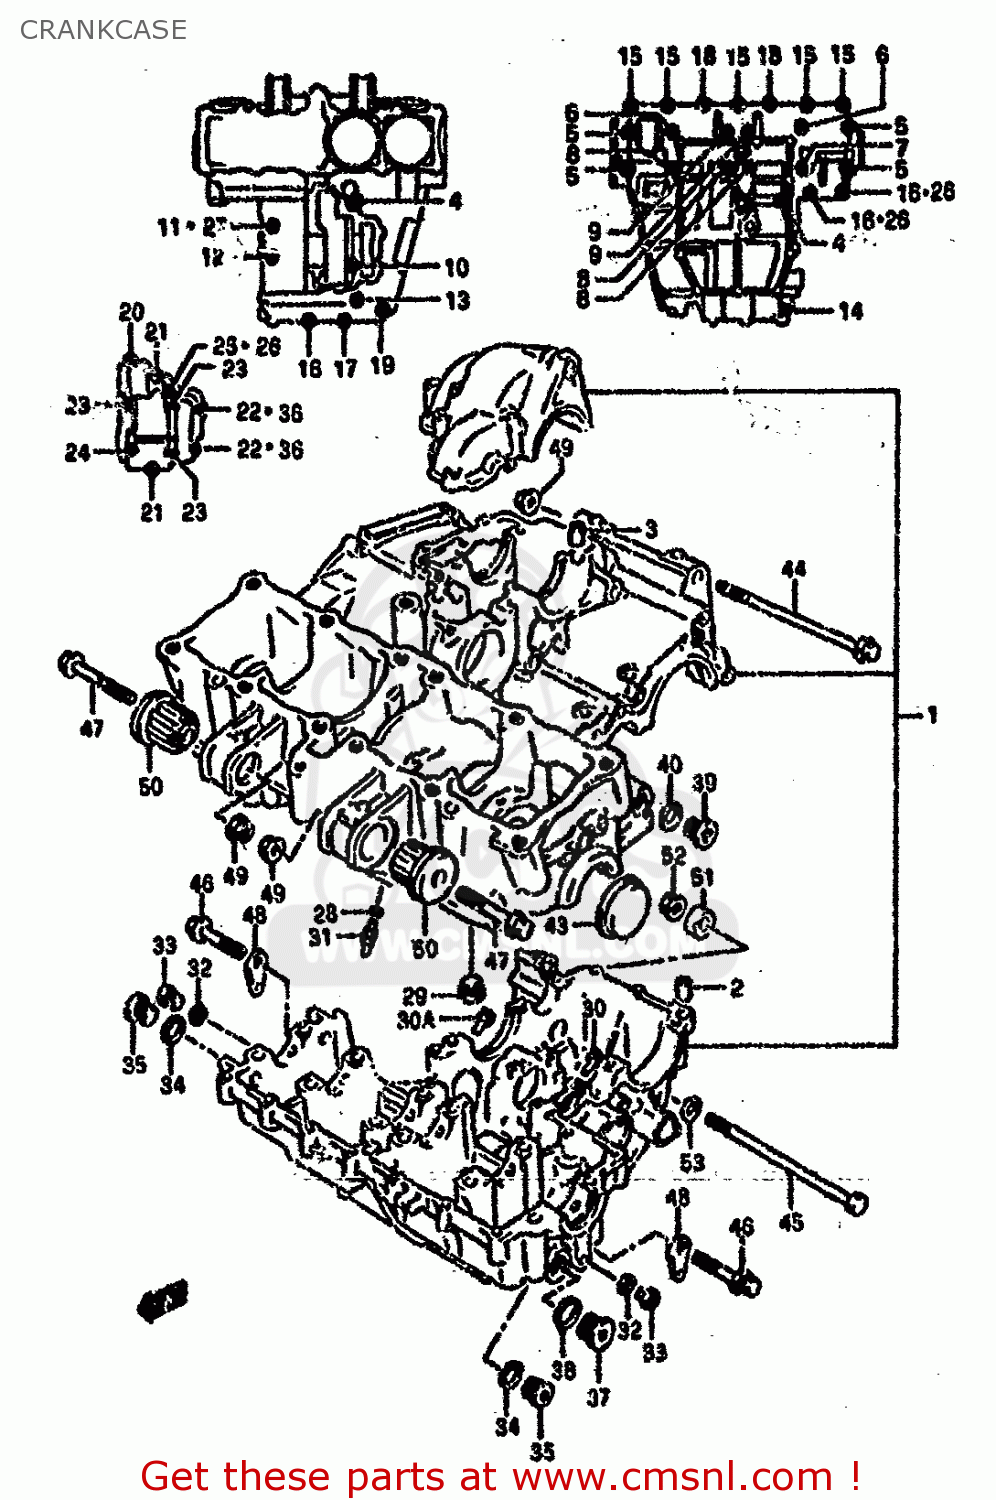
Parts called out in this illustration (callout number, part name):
1	CRANKCASE SET
2	PIN(10.4X13X22)
3	PIN
4	BOLT(6X105)
5	BOLT 9X80
6	BOLT(9X95)
7	BOLT(9X105)
8	BOLT(9X115)
9	BOLT(9X60)
10	BOLT
11	BOLT
12	BOLT
13	BOLT
14	BOLT
15	BOLT
16	BOLT
17	BOLT
18	BOLT
19	BOLT
20	BOLT,CL.COVER
21	BOLT
22	BOLT
23	BOLT,CL.COVER
24	BOLT
25	BOLT(6X145)
26	GASKET(6.2X13X1.2) (NAS)
27	GASKET(8.2X14X1) (NAS)
28	O RING(D:1.2,ID:4)
29	PLUG,CRANKCASE,UPPER
30	JET
30A	JET(140)
31	JET,OIL GALLERY
32	GASKET(10X14X3.6) (NAS)
33	PLUG(10X6.8)
34	GASKET(16X22X2) (NAS)
35	PLUG
36	GASKET(5.8X11X1.2) (NAS)
37	PLUG(22X11)
38	GASKET(22X27X2) (NAS)
39	PLUG
40	GASKET(13.8X18.8X4.8) (NAS)
41	BEARING,CRANK THRUST(GREEN)
42	BEARING,CRANK THRUST(GREEN)
43	PLUG
44	BOLT 10X150
45	BOLT,ENGINE MOUNTING,REAR,LOWER
46	BOLT
47	BOLT
48	NUT,ENGINE MOUNT,LOWER
49	NUT
50	BUSH,ENGINE MOUNTING
51	SPACER,ENGINE MOUNTING (L:13)(AL)
52	NUT 12MM
53	WASHER
